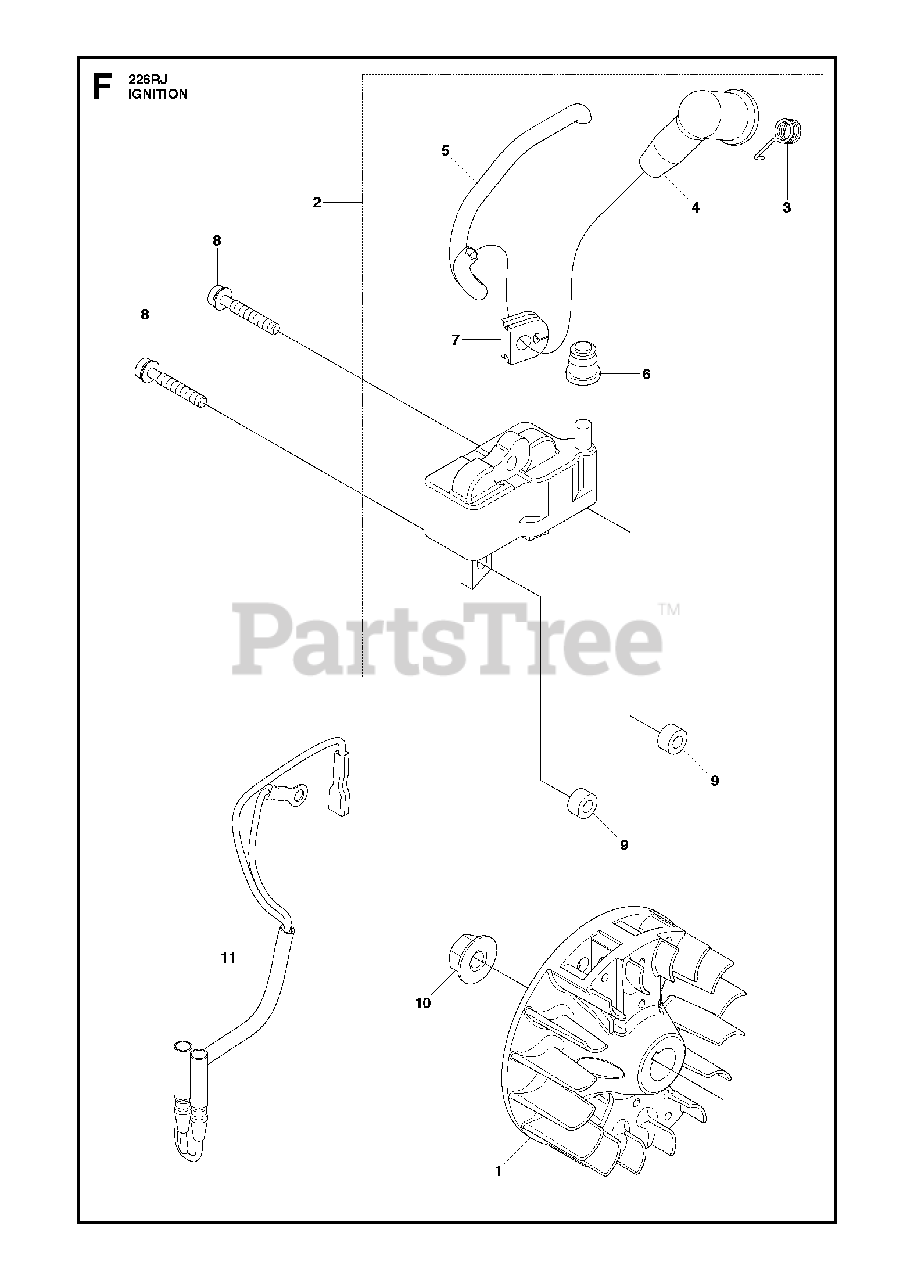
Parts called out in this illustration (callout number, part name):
3	SPRING
4	CAP
5	CORD
6	CAP
7	GROMMET
9	SPACER
10	NUT
